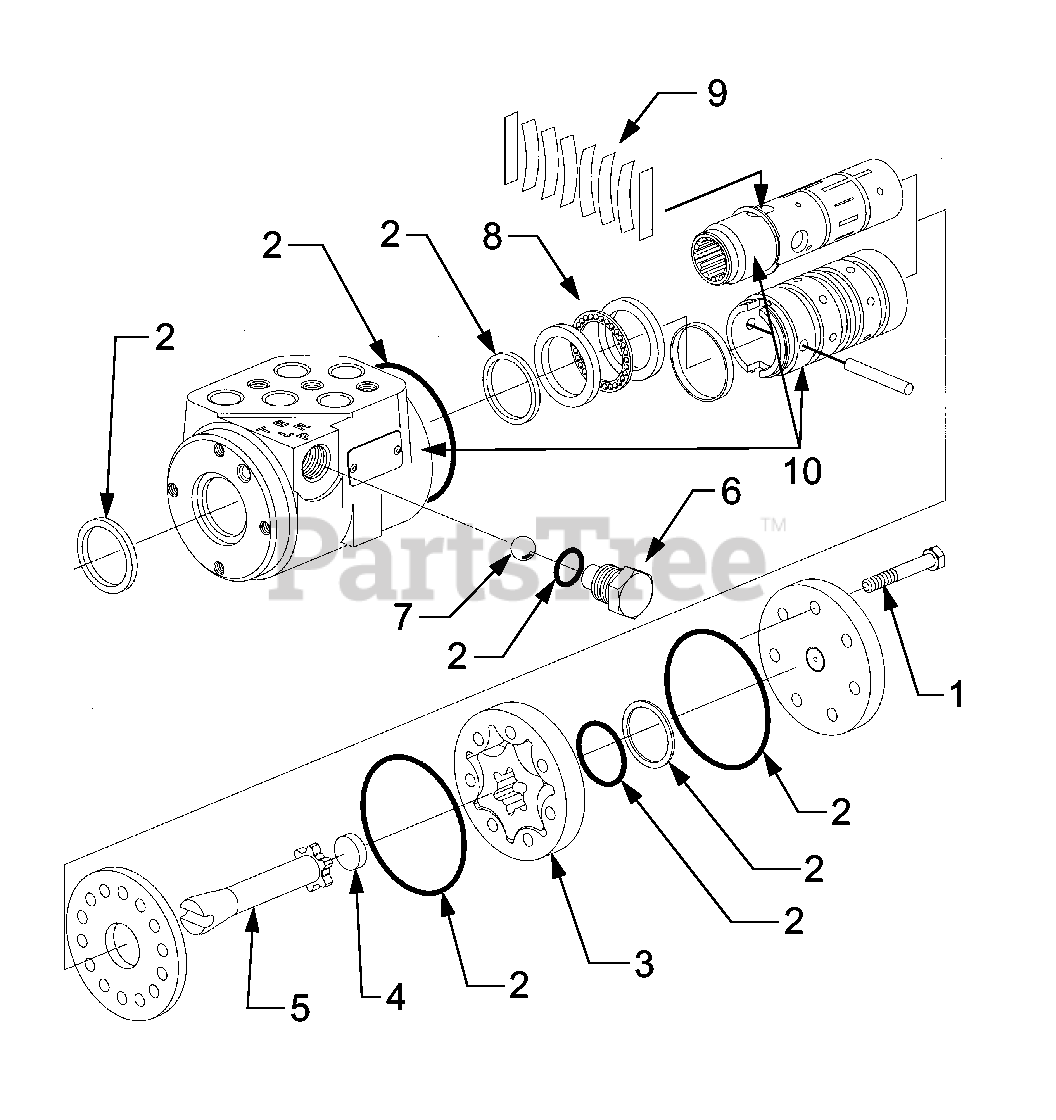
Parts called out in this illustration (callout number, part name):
1	Screw, Hex Cap, 1.57" Lg.
2	Seal Kit
3	Gerotor Assembly
4	Spacer, .240 Lg.
6	Plug, Manual Check
7	Ball, Manual Check
9	Spring Kit, Centering
10	Spool, Sleeve and Housing
